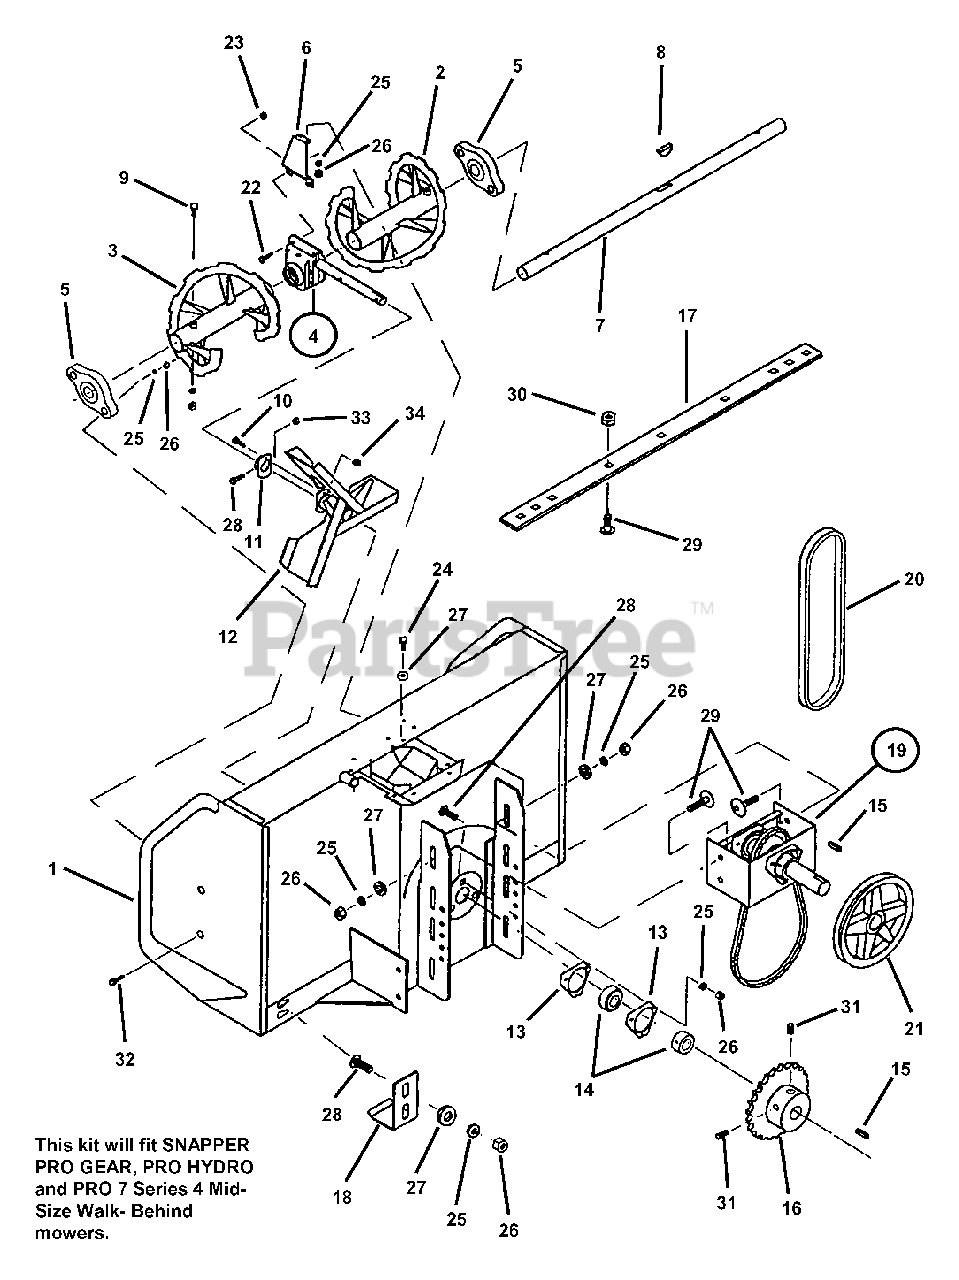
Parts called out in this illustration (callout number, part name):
2	AUGER, Right Hand (weldment)
3	AUGER, Left Hand (weldment)
4	ASSEMBLY, Worm Gear
5	BEARING
6	SUPPORT, Worm Gear
7	SHAFT, Output
8	KEY, Woodruff
9	SHEAR BOLT, 5/16-18 x 2-1/4"
10	SHEAR BOLT, 1/4-20 x 1"
11	SHEAR PLATE, Fan Adapter
12	ASSEMBLY, Fan
13	FLANGE, Bearing
14	BEARING, w/Locking Collar
15	KEY, 1/4" Square x 1"
16	SPROCKET, 40838
17	CUTTING EDGE
18	SKID SHOE
19	ASSEMBLY, Reduction Box
20	BELT, SP Models w/Kohler Engine
21	PULLEY BK67
22	BOLT, 5/16-18 x 1-1/2" Hex
23	NUT, 5/16-18 Hex
24	BOLT, 5/16-18 x 3/4" Hex
25	WASHER, 5/16" Lock
26	NUT, 5/16-18 Hex
27	WASHER, 3/8" Flat
28	BOLT, 5/16-18 x 1" Square Neck Carriage
29	BOLT, 5/16-18 x 3/4" Square Neck Carriage, Grade 5
30	NUT, 5/16-18 Stover
32	BOLT, 3/8-16 x 1-1/4" Hex
33	NUT, 5/16-18 Stover
34	NUT, 1/4-20 Hex Nyloc
